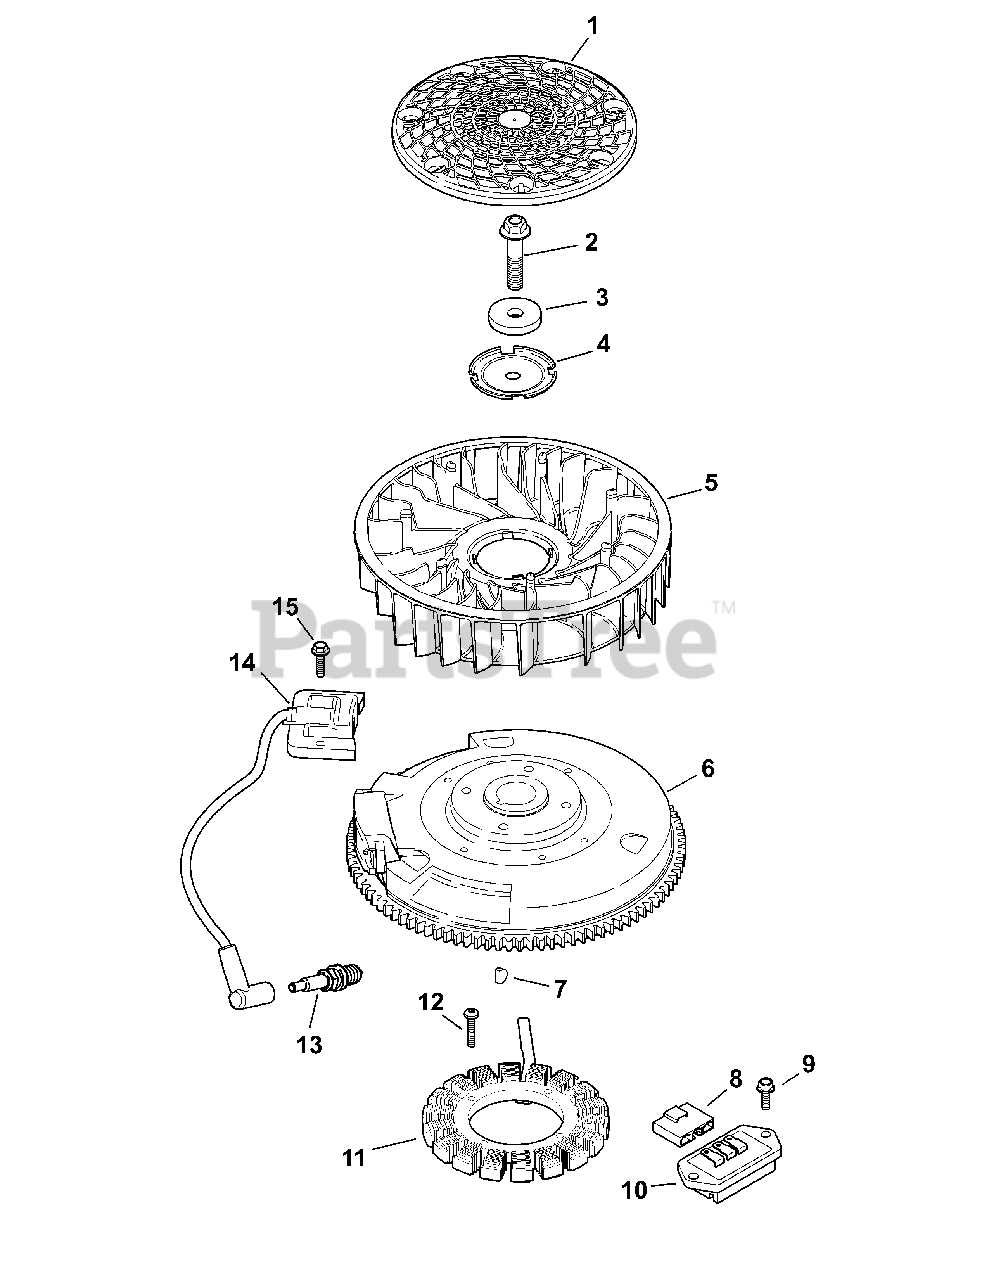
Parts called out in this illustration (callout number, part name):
1	Screen, Grass
2	Screw, FLG M10X1.5X45
3	Washer, Flat 13/32"
4	Plate, Fan Mounting
5	Fan
6	Flywheel
7	Key, 3/16" x 5/8"
8	Connector (3 Contact)
9	Screw, Hvy Flg M5 x 0.8 x 16
10	Rectifier-Regulator
11	Kit, 15 Amp Stator
12	Screw, TRX HD Drive Fastener
14	Module, Ignition (CDI Fixed)
15	Screw, FLG THD FRM M5 x 0.8 x 20
